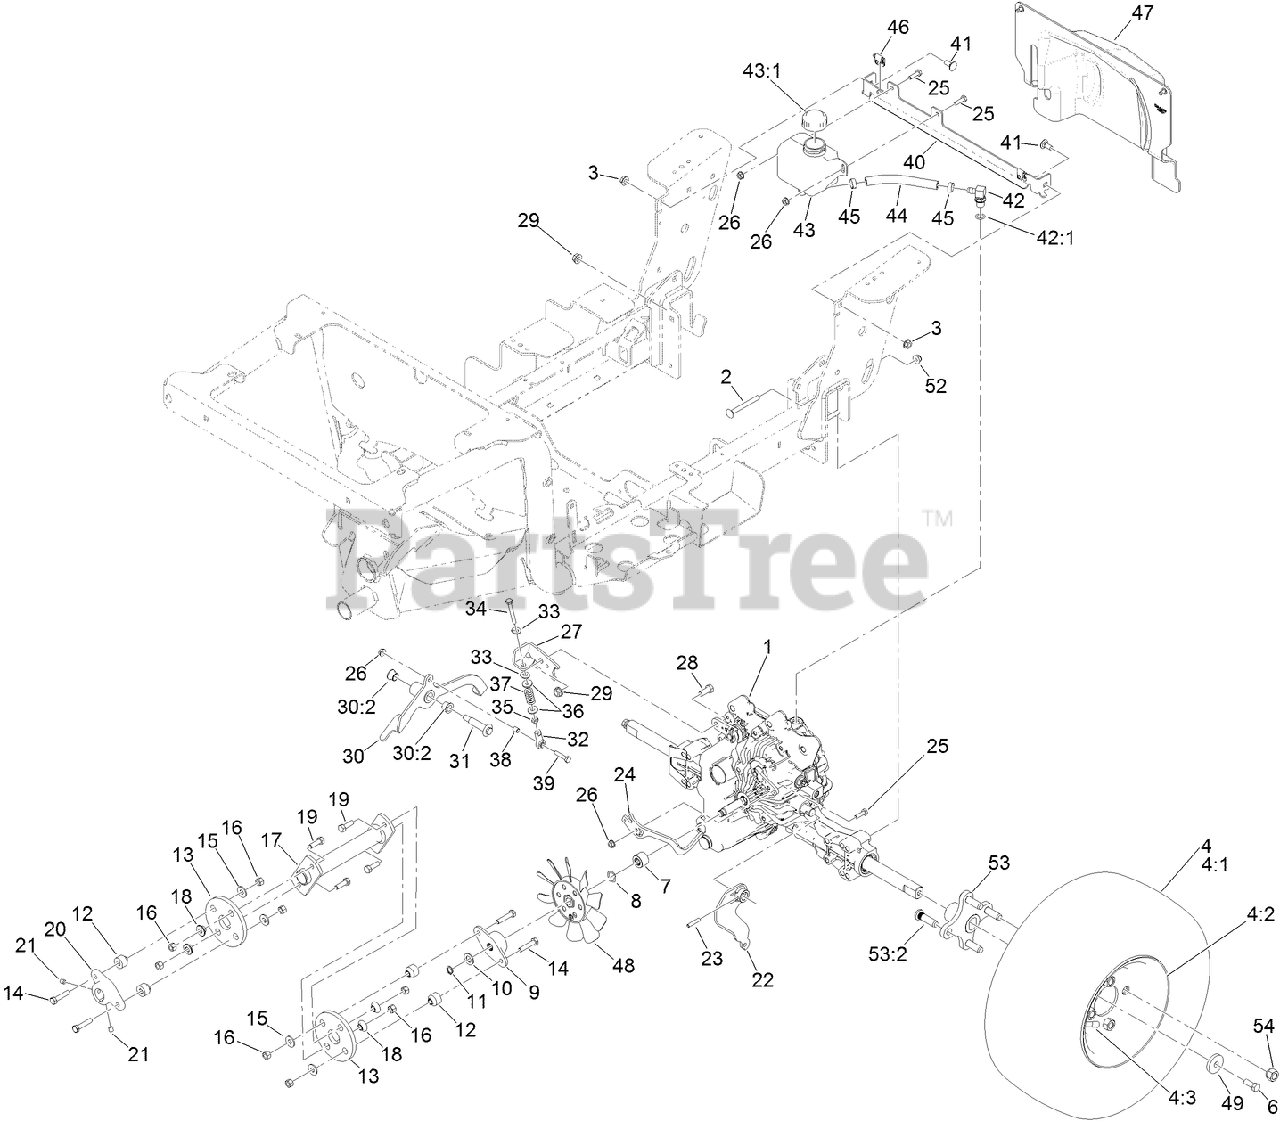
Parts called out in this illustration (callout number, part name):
1	TRANSAXLE
2	SCREW-CARR
3	NUT-HF
4	WHEEL AND TIRE ASM (GREY)
4:1	TIRE-4 PLY
4:2	WHEEL (GREY)
6	SCREW-HH
7	SPACER-SHAFT, INPUT
8	WASHER-SPRING
9	HUB-SHAFT, TRANSAXLE
10	SPACER
11	RING-RETAINING
12	SPACER-COUPLING, RUBBER
13	COUPLING-RUBBER
14	SCREW-HH
15	WASHER-FLAT
16	NUT-HEX
17	SHAFT-DRIVE
18	SPACER-COUPLER, RUBBER
19	SCREW-HH
20	HUB-SHAFT, ENGINE
21	SETSCREW
22	ARM-MOTION
23	PIN-SPIRAL
24	ARM-RELEASE
25	SCREW-HH
26	NUT-HF
27	ARM-BRAKE
28	SCREW-HH
29	NUT-HF
30	BRAKE LEVER ASM
30:2	BEARING-FLANGE
31	BOLT-SHOULDER
32	ROD END-BALL JOINT
33	WASHER-SPRING
34	SCREW-HH
35	NUT-JAM
36	WASHER-FLAT
37	SPRING-COMPRESSION
38	SPACER
39	SCREW-HH
40	BRACKET-MOUNT, TANK
41	SCREW-CARR
42	FITTING-90 DEG
42:1	O-RING
43	TANK ASM
43:1	CAP-TANK
44	HOSE-EXPANSION
46	RECEPTACLE-CLIP, MINI
47	TRANSAXLE COVER ASM
48	FAN-7 INCH
49	WASHER-CLUTCH
52	NUT-HF, NI
53	WHEEL HUB ASM
53:2	STUD-TYPE, DRIVE
54	NUT-LUG
